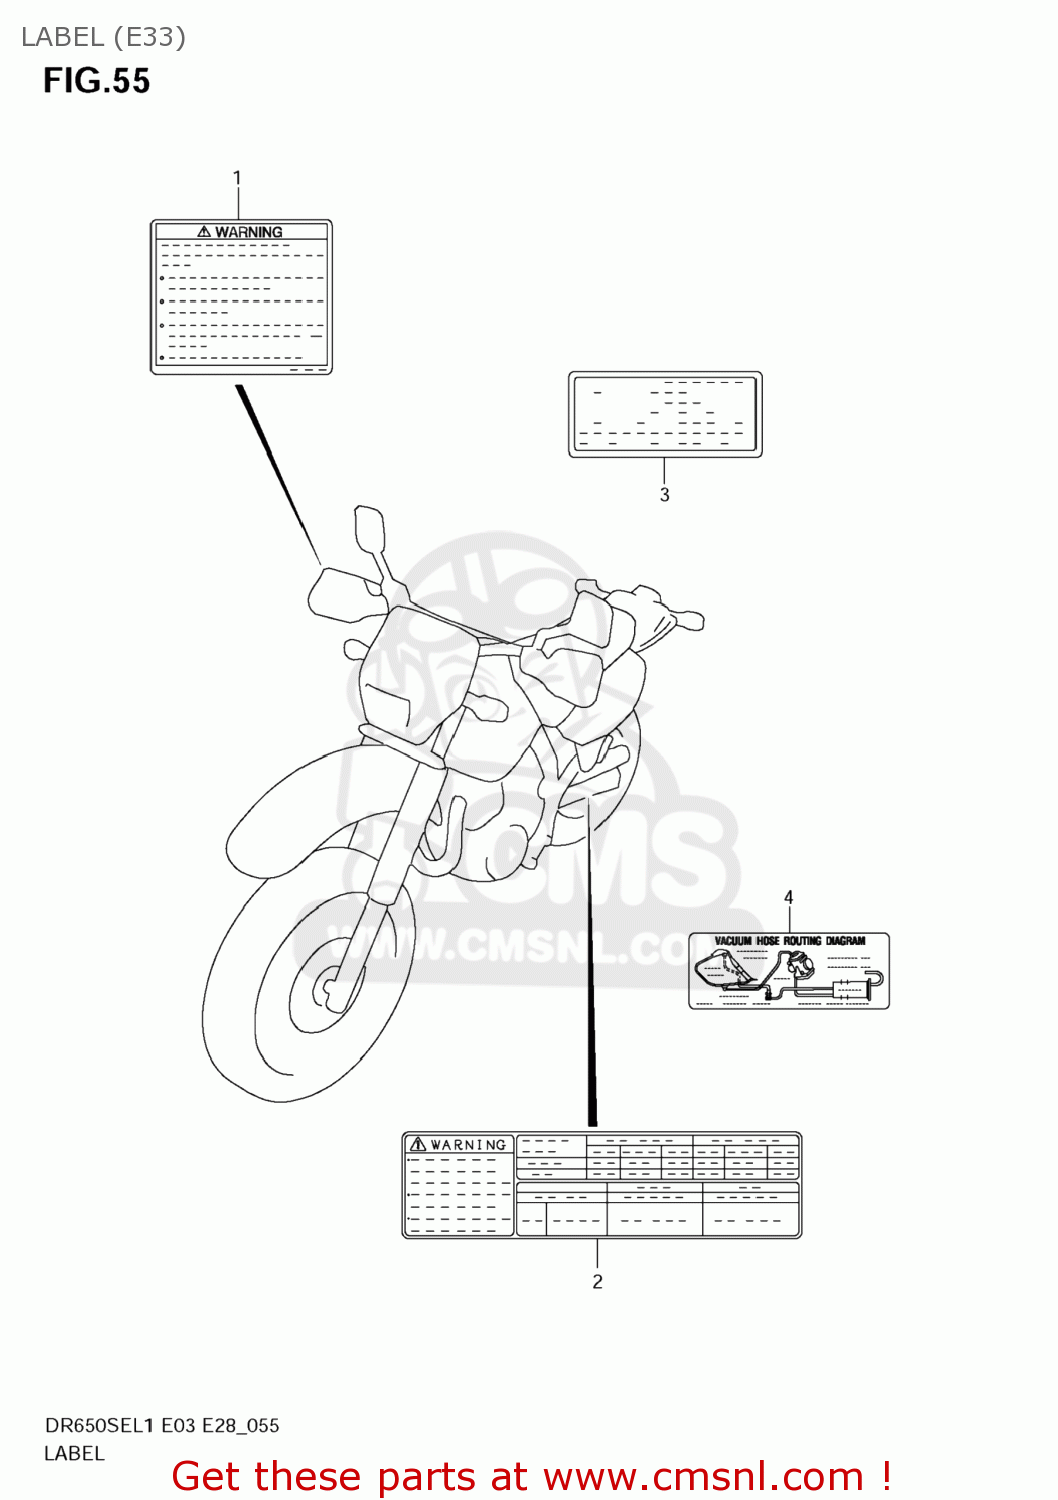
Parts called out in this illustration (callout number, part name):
1	LABEL,GENERAL WARNING
2	LABEL,TIRE INFORMATION
3	LABEL,MANUAL NOTICE
4	LABEL,PIPING DIAG
5	MANUAL,OWNER'S
